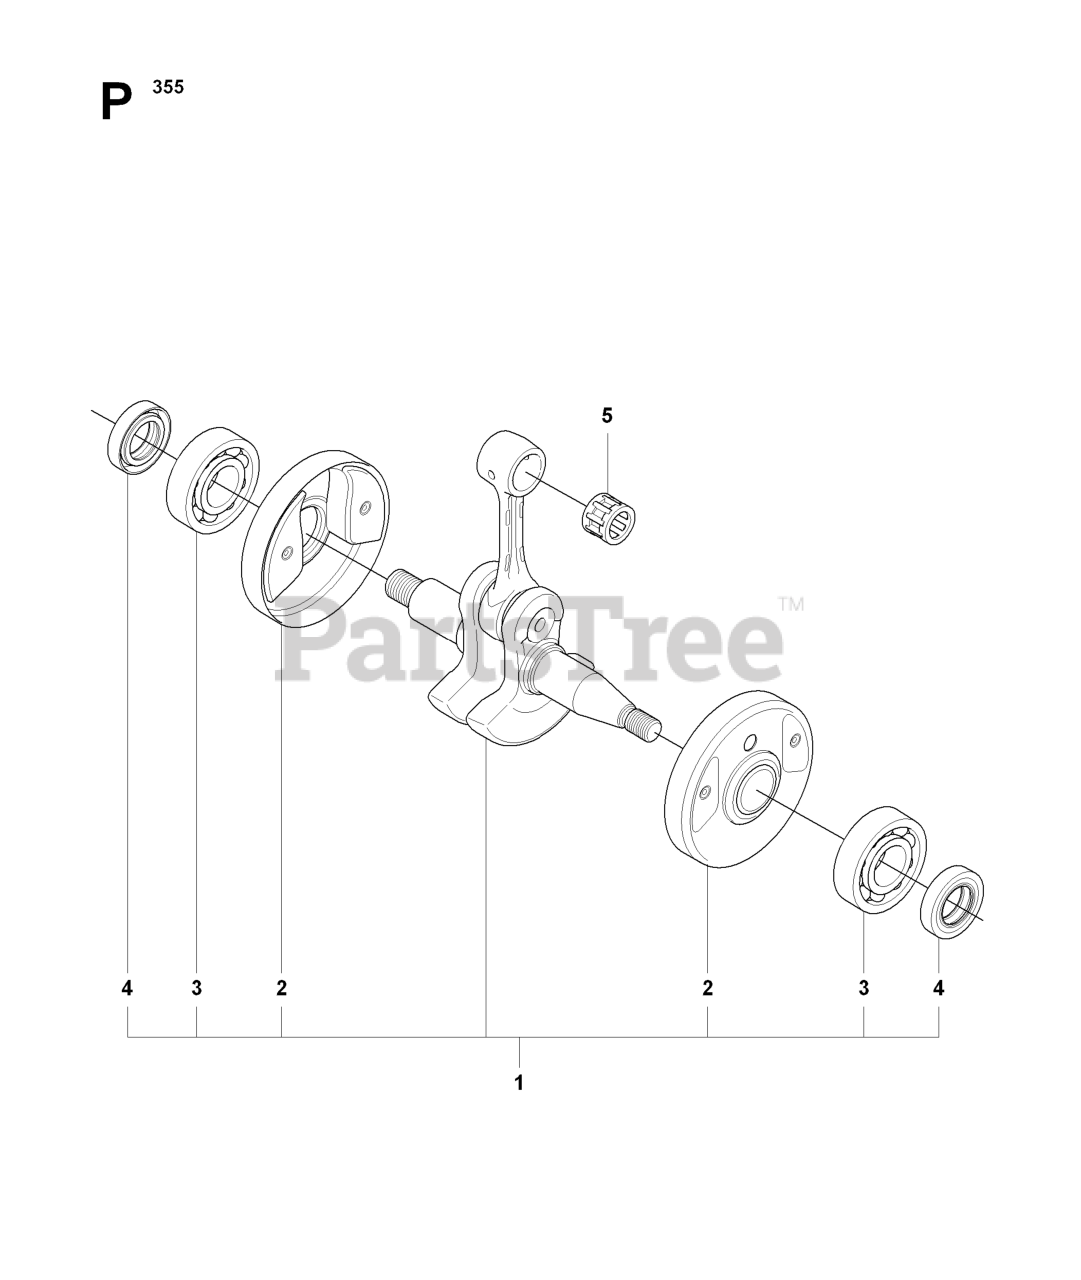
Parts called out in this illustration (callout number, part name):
1	CRANKSHAFT
3	BALL BEARING-6202-C3 SKF
4	SEALING RING
5	SUPPORT BUSHING
